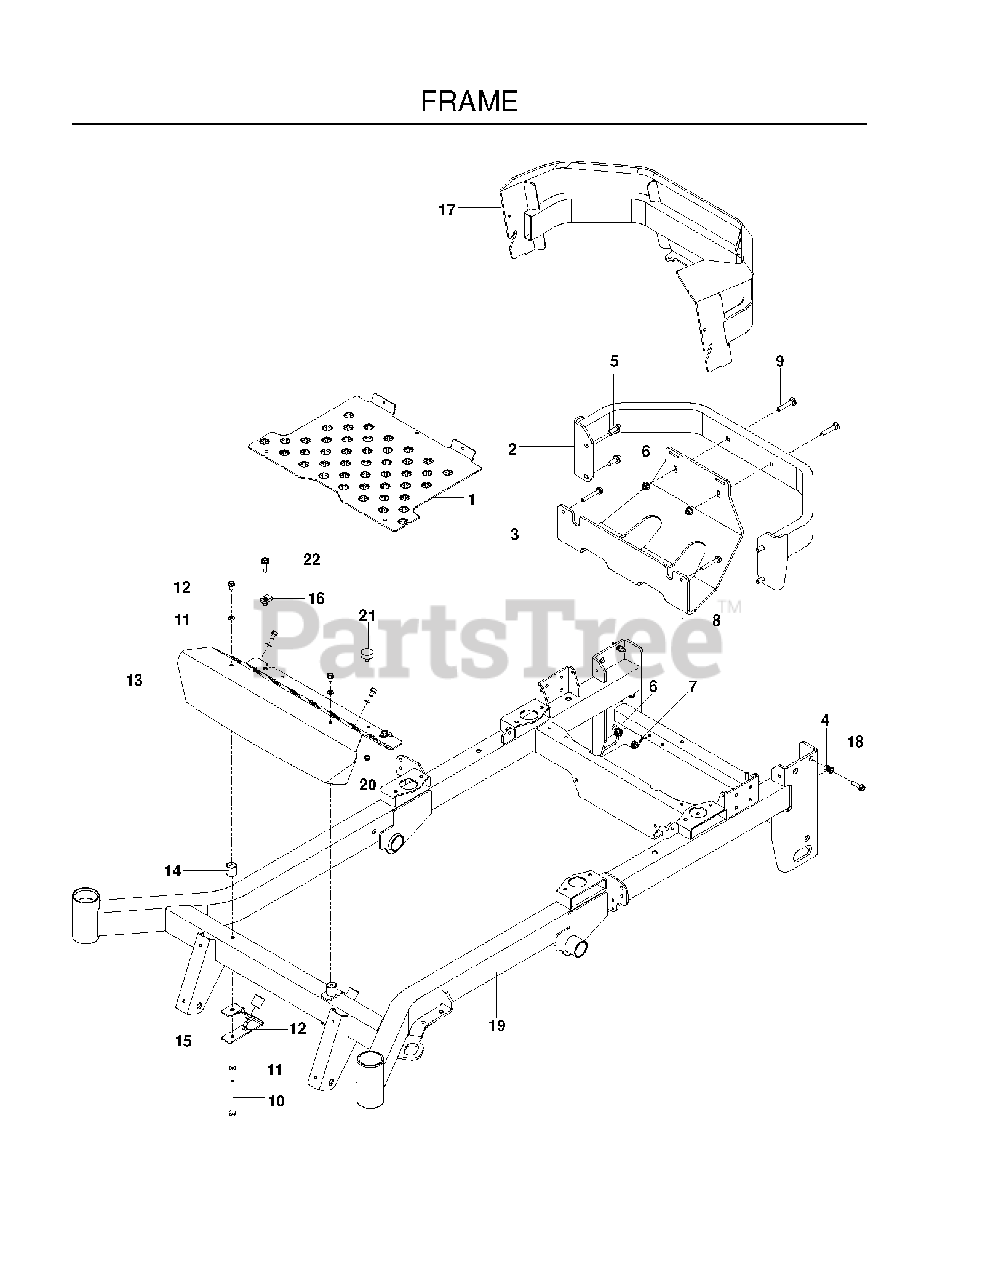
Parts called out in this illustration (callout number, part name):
1	PLATE, FLOOR PAN, OR
2	BUMPER.REAR.ORANGE
3	PLATE, SKID GRAY
4	NUTSERT 5/16-18 THICK GRIP
5	HHFS 3/8-16 X 1 GRD 5 ZD
6	NUT 3/8-16 HEX FLG NYLOC ZD
7	5/16-18 NYLOC FLANGE NUT
8	HHFS 5/16-18 X 2.25 GD 5
9	RHSNB 3/8C X 2
10	HHFS 5/16-18 X 3 3/4
11	WASH 5/16 DISC SPRING ZD
12	SCR 5/16-18 X 1/2 SELFTAP ZN
13	PLATE, FOOT REST, OR
14	MOUNT, F/F INSERT
15	BRACKET, REST MOUNT
16	U-CLIP 5/16-18 NUT RETAINER
17	GUARD, REAR, GRAY
18	HHFS 5/16-18 X 1.25 TPBLT GD 5
19	FRAME W/DECALS PZ 72
20	JAM NUT 1/4C (2 2 PW01)
21	BUMPER, 1/4-20 STUD, 1/4
22	RP BLT 5/16-18 X 1 THRD FORM D
